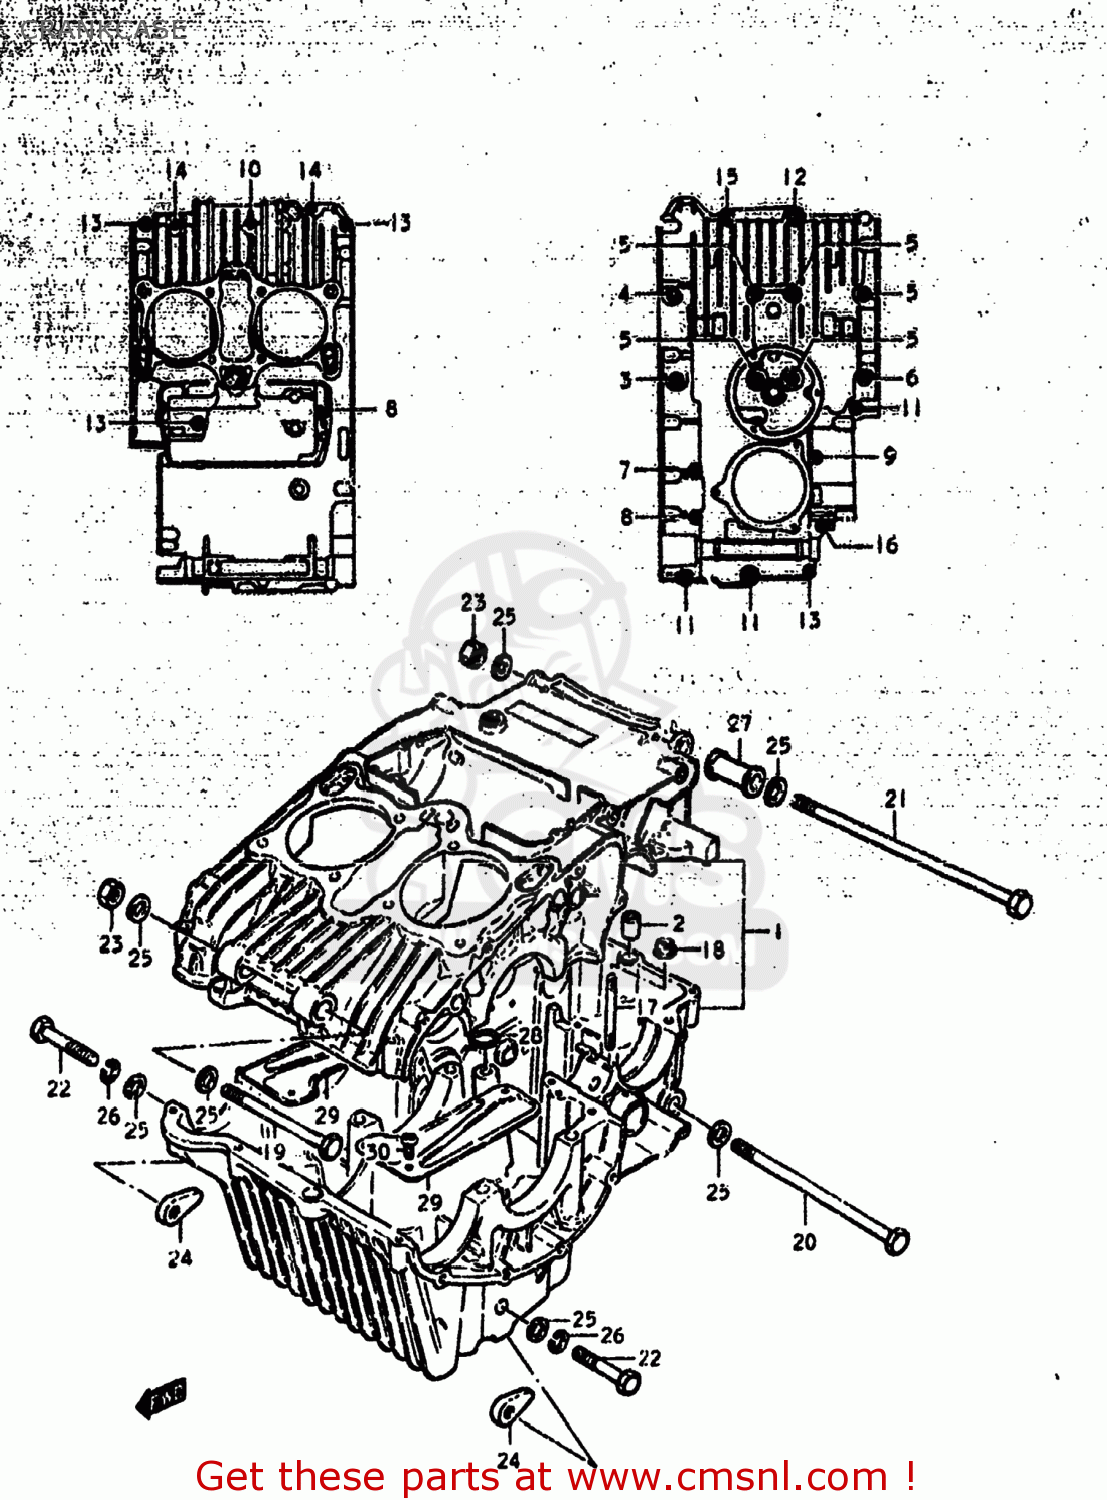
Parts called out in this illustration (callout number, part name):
1	CRANKCASE SET
2	PIN
3	BOLT
4	BOLT (8X95)
5	BOLT 8X90
6	BOLT
7	BOLT
8	BOLT (6X90)
9	BOLT (6X70)
10	BOLT 6X65
11	BOLT (6X60)
12	BOLT,UNDER
13	BOLT
14	BOLT 6X35
15	BOLT
16	BOLT (8X45)
17	STUD BOLT
18	NUT
19	BOLT
20	BOLT 10X160
21	BOLT 10X265
22	BOLT
23	NUT
24	NUT
25	WASHER
26	LOCK WASHER
27	SPACER,ENGINE MOUNT
28	O-RING
29	PLATE,OIL SEPARATOR
30	SCREW
